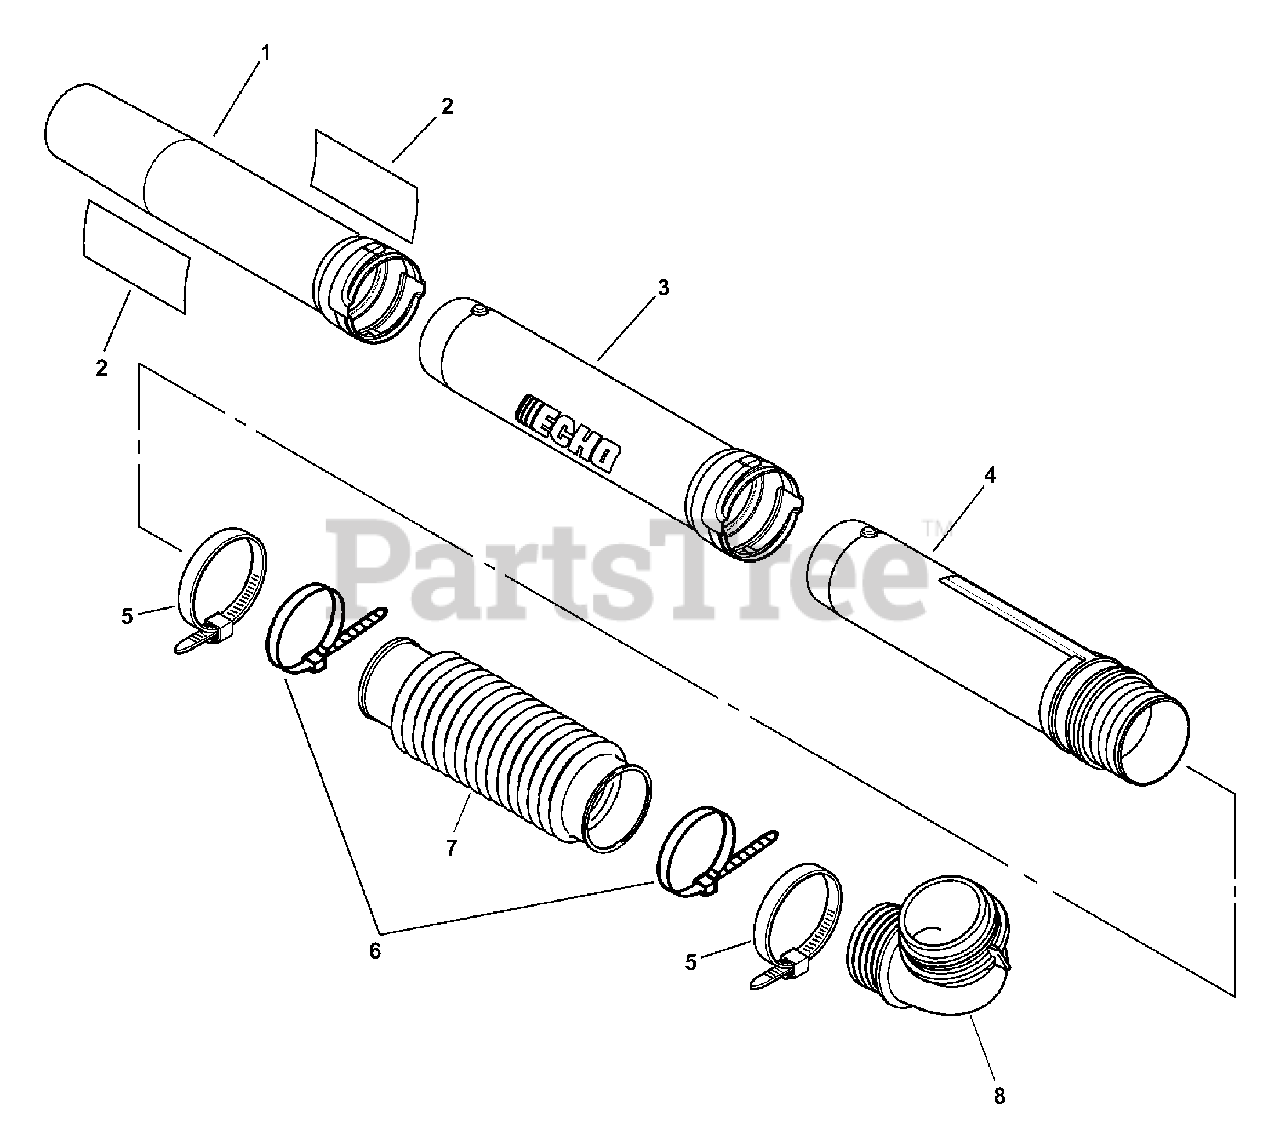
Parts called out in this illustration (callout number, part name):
1	TUBE, BLOWER - STRAIGHT
2	LABEL - ECHO
3	TUBE, BLOWER - STRAIGHT
4	TUBE, BLOWER - SWIVEL
5	CLAMP 58.7 MM / 82.5 MM
6	STRAP, TIE - LARGE
7	TUBE, BLOWER - FLEXIBLE
8	TUBE, BLOWER - ELBOW
